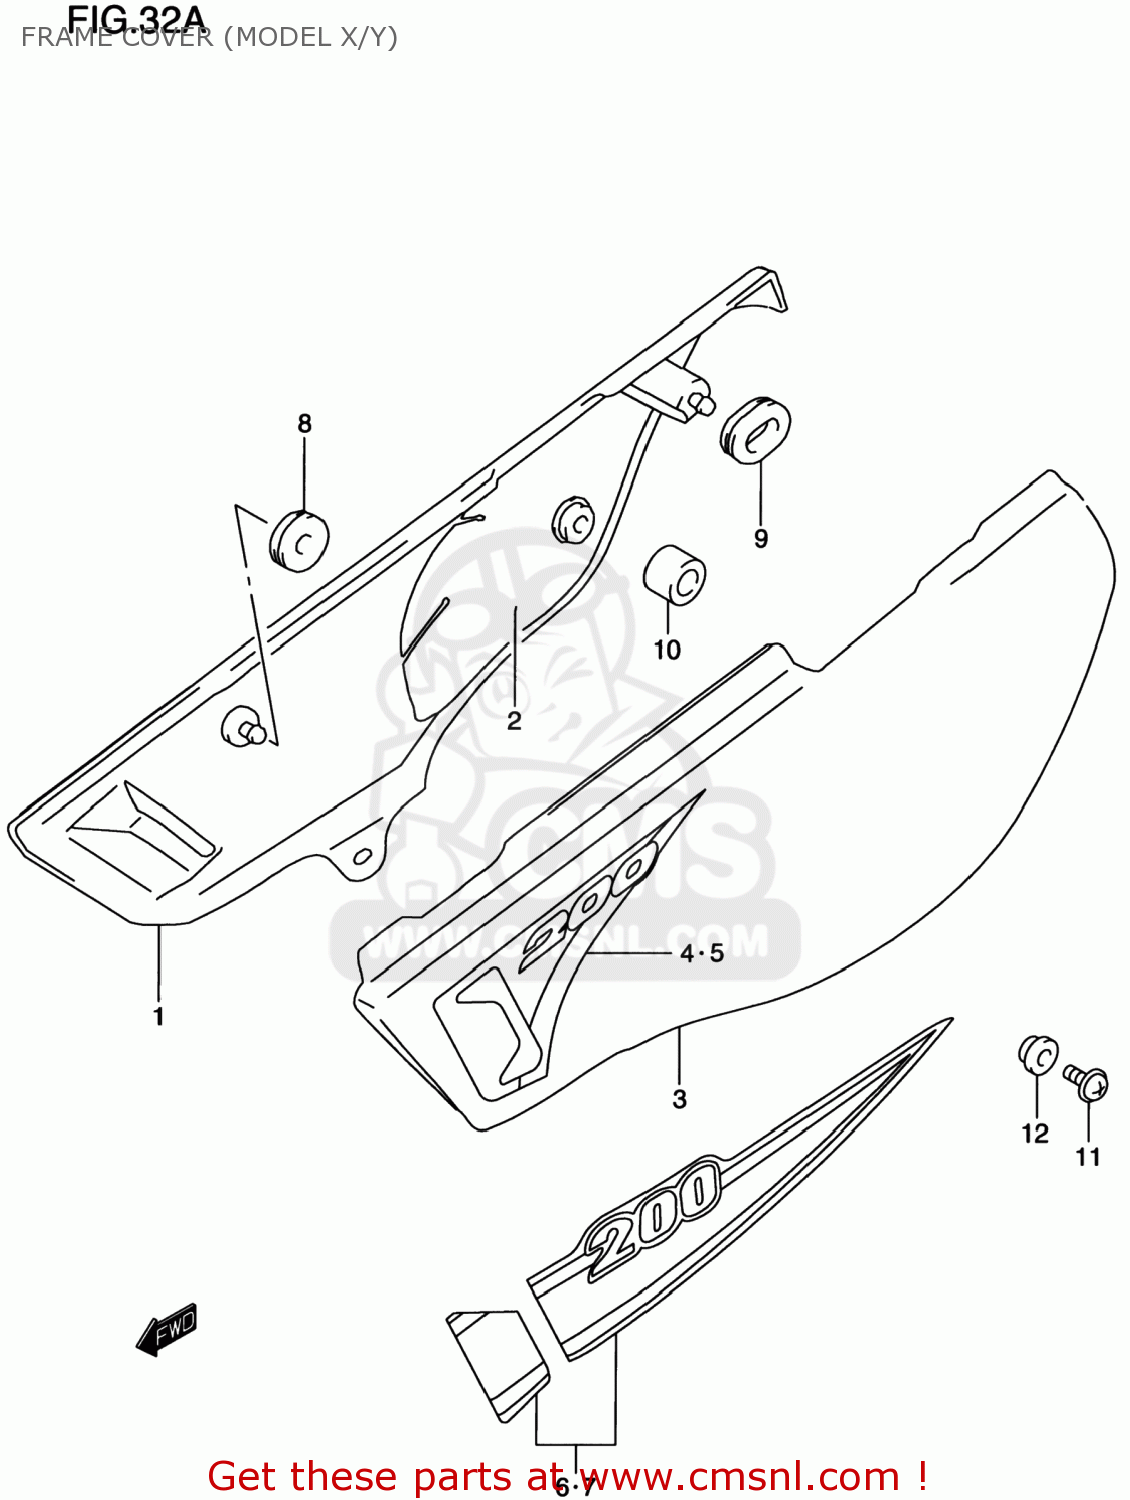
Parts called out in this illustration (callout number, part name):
1	COVER,FRAME,R(WHITE)
2	SHIELD,FRAME COVER,R
3	COVER,FRAME,L(WHITE)
4	TAPE,FRAME COVER,RIGHT
5	TAPE,FRAME COVER,LEFT
6	TAPE,FRAME COVER,R
7	TAPE,FRAME COVER,L
8	CUSHION
9	CUSHION
10	CUSHION
11	SCREW(6X16)
12	WASHER
